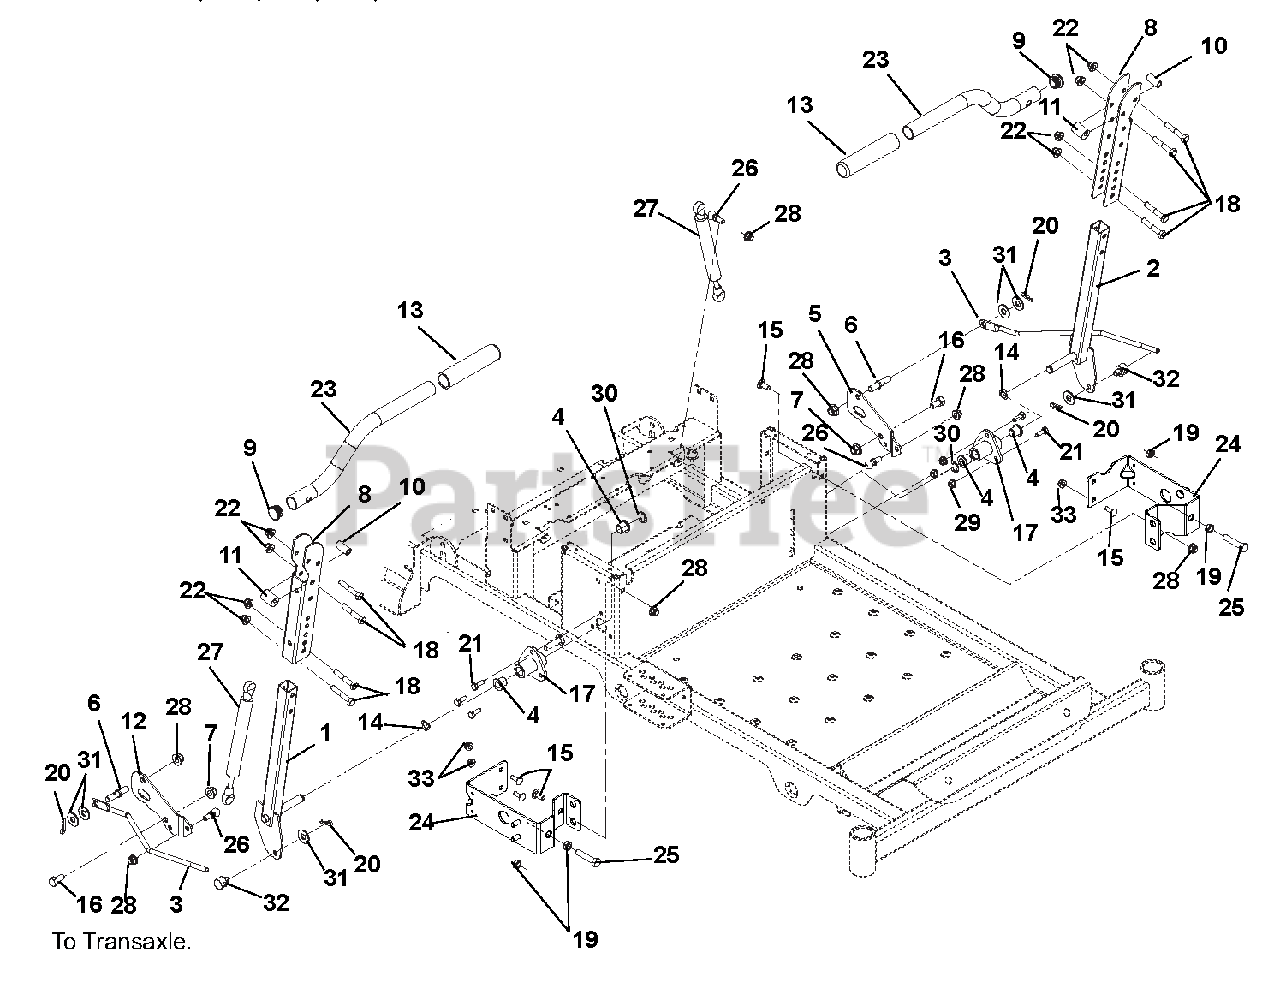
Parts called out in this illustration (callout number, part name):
1	WMT, RH CONTROL ARM
2	WMT, LH CONTROL ARM
3	LINK, STEERING
4	BSHG, FLG .500X.625.620X.857
5	PLATE, DAMPER (LH)
6	PIN, TRANS
7	@NUT-LK-NYL-FLG .38-16 YWZC
8	CHANNEL, UPPER HANDLEBAR
9	CAPLUG, HANDLEBAR
10	BSHG, SPCR .330X.500X1.01 PM
11	BSHG,ECCEN .328X.750X1.01 PM
12	PLATE, DAMPER RH
13	HANDLE GRIP
14	WSHR-FL-STL .505X.880X.072 YWZ
15	@BLT-RHDSSQNK .31-18X.75 G5YZ
16	@BLT-HEX .38-16X.75 GR5 YWZC
17	BUSHING, FLANGED
18	BLT-HEX .31-18X1.75 GR5 PDB
19	NUT-HEX-JAM .375-16 YWZC
20	PIN-HAIR INT .08X.18X1.18 YWZC
21	@BLT-HEX .25-20X.75 GR5 YWZC
21	SCR-TAP .25-20X.50 HWH TR YWZ
22	NUT, .31-18 NYLOC FLANGE PDB
23	HANDLE, STEERING
24	WMT, STEERING STOP
24	BRKT, SPEED ADJ/SEAT PIVOT
25	BLT-HEX .375-16X1.750 FTD YWZC
26	STUD- BALL
27	DAMPER, STABILUS
28	@NUT-LK-NYL-FLG .31-18 YWZC
29	@NUT-LK-TOP-FLG .25-20 YWZC
30	RG-RTNG-EXT .500X.042 (E)
31	@WSHR-FL-STL.438X1.00X.083 YWZ
32	TRUNNION, BRAKE .31-18 UNC
33	@NUT-LK-NYL-FLG .25-20 YWZC
